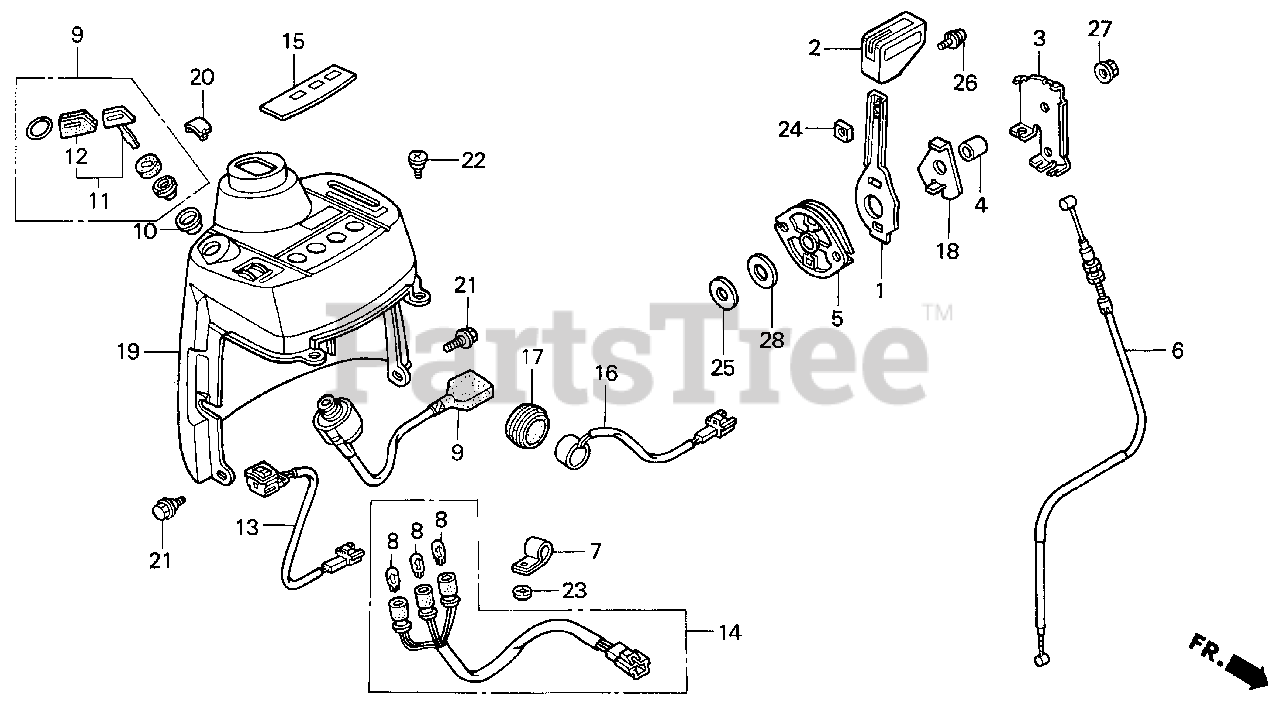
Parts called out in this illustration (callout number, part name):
1	LEVER, THROTTLE
2	KNOB, THROTTLE LEVER
3	BRACKET, THROTTLE LEVER
4	COLLAR, THROTTLE LEVER
5	REEL, THROTTLE CABLE
6	CABLE, THROTTLE
7	CLAMP, IGNITION WIRE
8	BULB, WEDGE BASE (12V 3.4W)
8	BULB (12V3.4W) (158)
8	BULB (12V3.4W2CP) (158) (NS)
9	SWITCH ASSY., COMBINATION
10	BASE, COMBINATION SWITCH
11	KEY ASSY., COMBINATION SWITCH
15	PANEL, INDICATOR
16	BUZZER, WARNING
17	GROMMET, PARKING BRAKE BUZZER
18	STOPPER, REEL
19	PANEL, INSTRUMENT *NH247* (ASSEMBLY GRAY)
20	MASK, HEAD LAMP SWITCH
21	BOLT, FLANGE (6MM)
22	SCREW, METER VISOR SETTING
23	NUT, PUSH (5MM)
24	NUT, SQUARE (4MM)
25	WASHER (20MM)
26	SCREW-WASHER (4X8)
27	NUT, FLANGE (6MM)
28	WASHER, THRUST (16.2X30X2.0)
